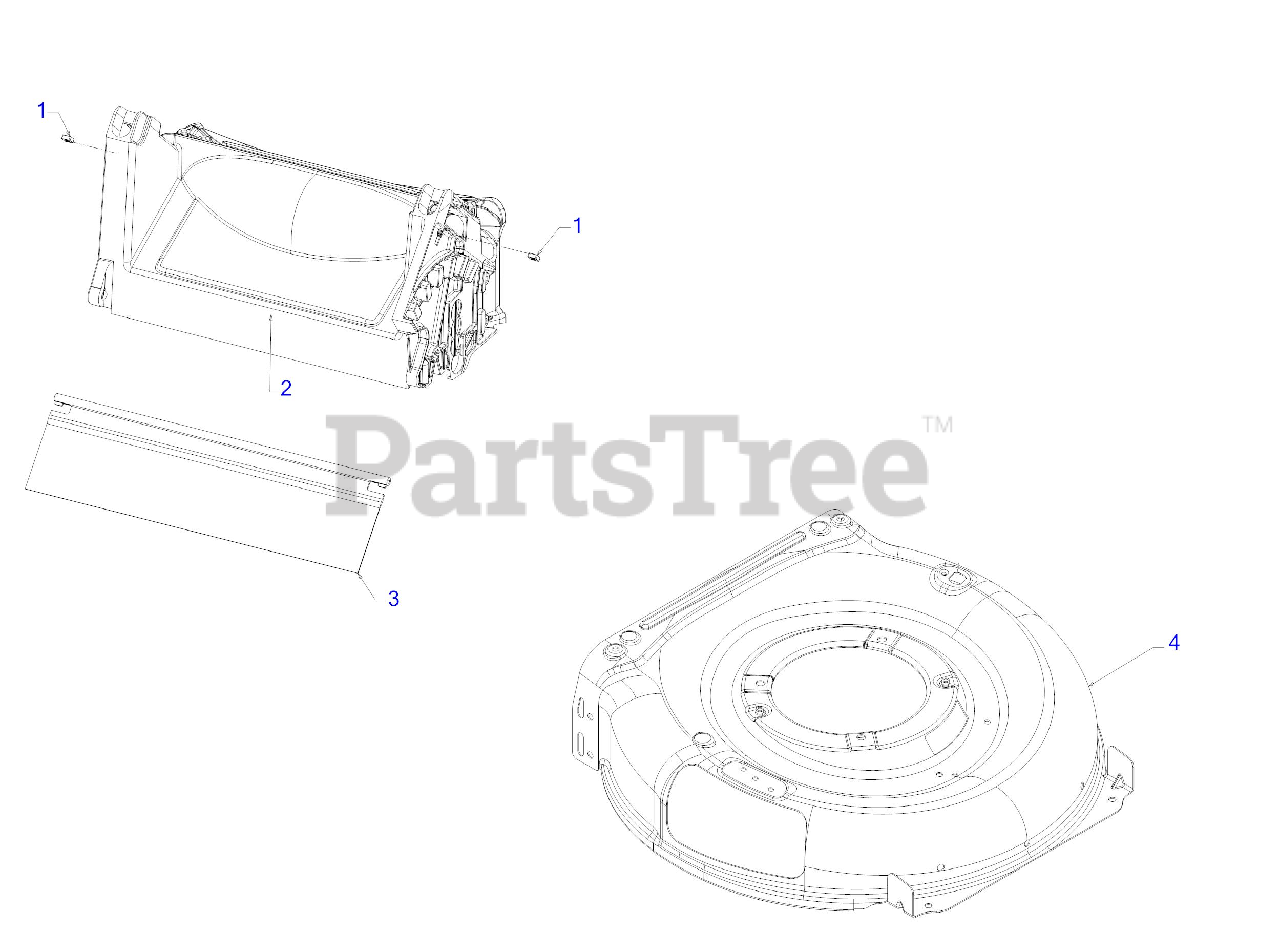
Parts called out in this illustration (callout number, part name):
1	SQUARE NUT 1/4-20
2	REAR BAFFLE ASSEMBLY
3	TRAILSHIELD
